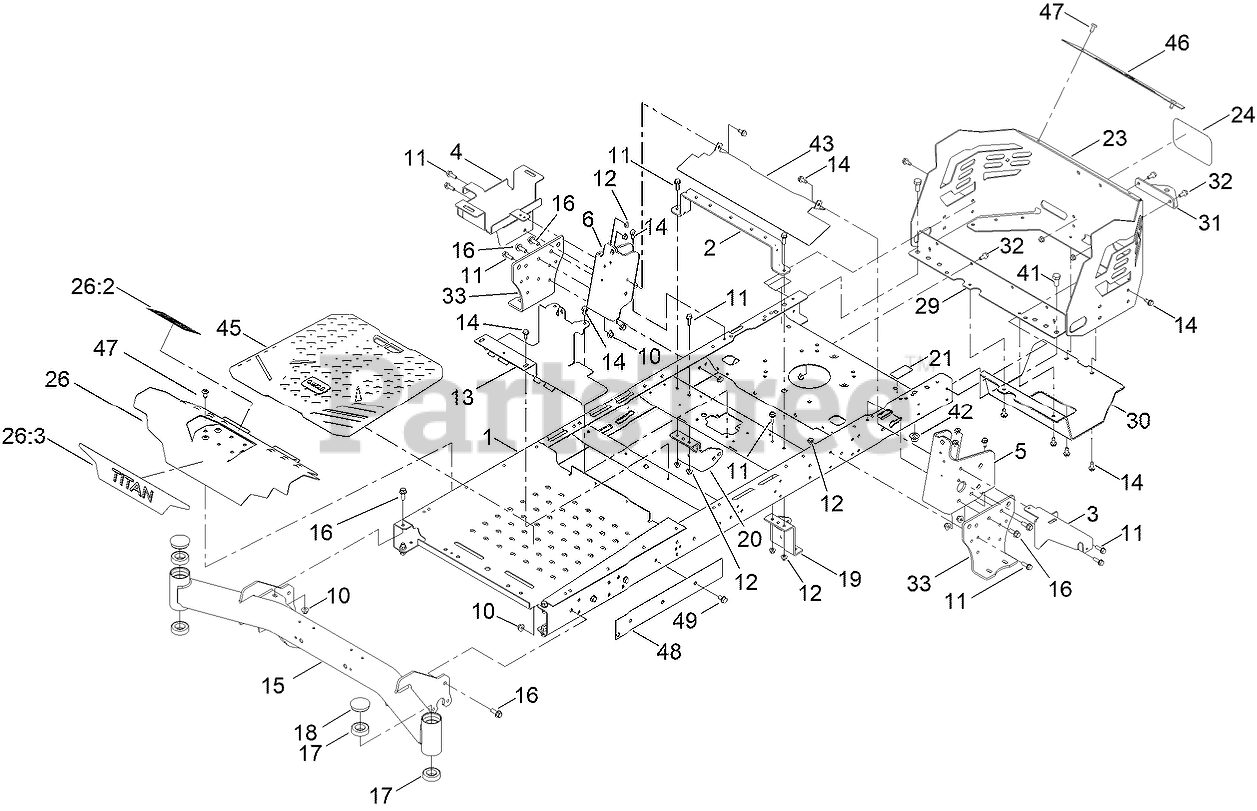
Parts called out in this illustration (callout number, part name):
1	FRAME ASM
2	BRACE-SEAT, REAR (WIDE)
3	BRACKET-SUPPORT, POD (LH)
4	TRAY-BATTERY
5	BRACKET-MOUNTING, LH
6	BRACKET-MOUNTING, RH
10	NUT-HF, NI
11	SCREW-HHF
12	NUT-HF, NI
13	BRACKET-MOUNT
14	SCREW-HWHTF
15	FRONT AXLE ASM
16	SCREW-HHF
17	BEARING-BALL
18	CAP-GREASE
19	MOUNT-HYDRO, FRONT (LEFT)
20	MOUNT-HYDRO, FRONT (RIGHT)
21	DECAL-BYPASS
23	GUARD-ENGINE
24	DECAL
26	FOOTREST-TITAN
26:2	DECAL-DANGER
26:3	DECAL-TITAN
29	CROSSMEMBER-REAR, WIDE
30	GUARD-MUFFLER
31	BRACKET-HITCH
32	SCREW-HHF
33	MOUNT-HYDRO
41	SCREW-HH
42	NUT-LOCK
45	FLOOR MAT
46	TRIM-GUARD, ENGINE
48	PLATE-FRAME
49	SCREW-HWHTF
